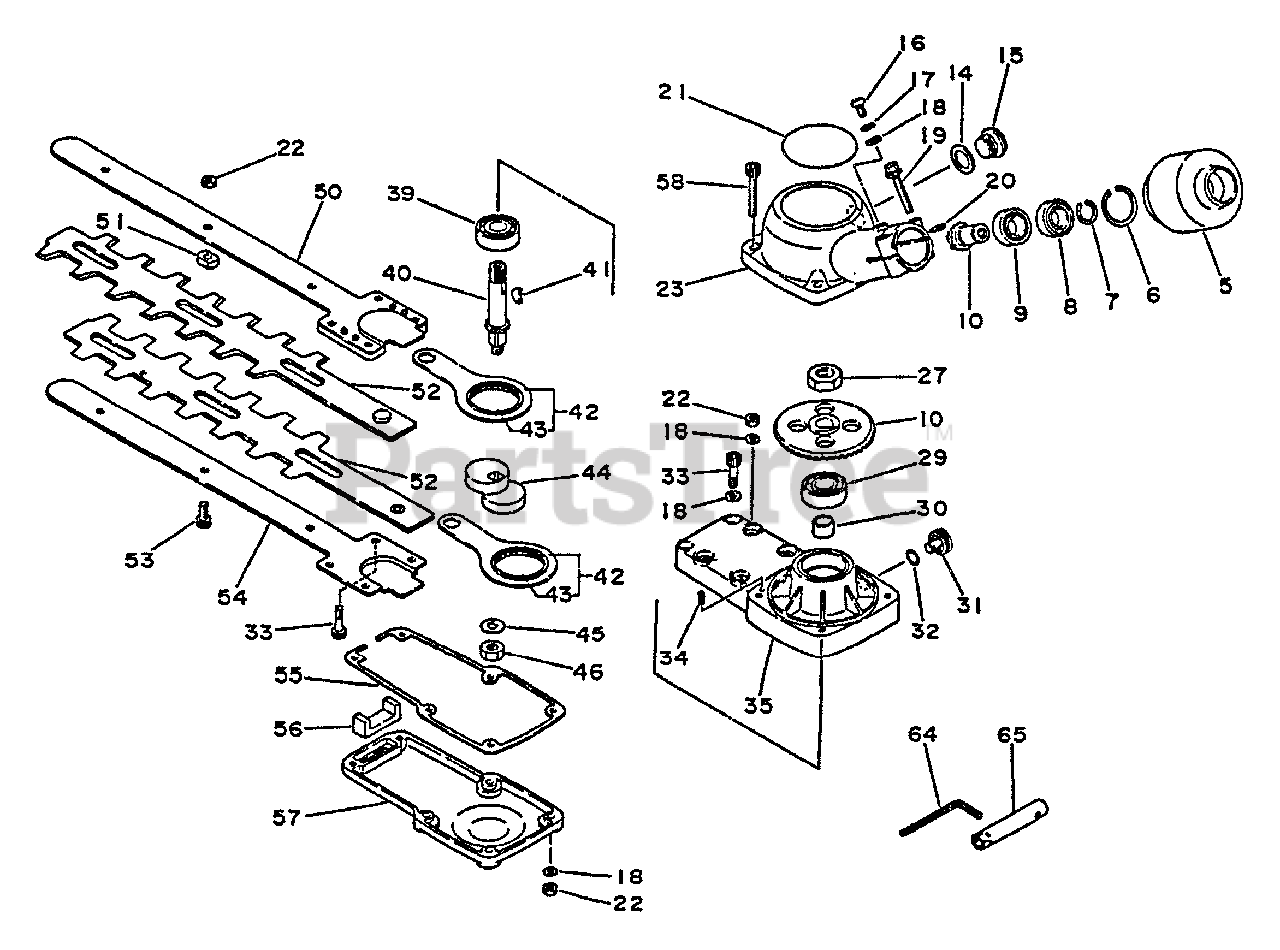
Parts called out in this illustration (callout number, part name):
6	RING, RETAINING - 28
7	RING, RETAINING - 12
8	BEARING, BALL - 6001
9	BEARING, BALL - 6001
10	GEAR SET
14	CASE, GEAR
15	FITTING, GREASE
16	SCREW - 5X10
17	LOCKWASHER - 5
18	WASHER - 5
19	BOLT - 5X35
21	LABEL
23	CASE, GEAR
27	NUT - 12
29	BEARING, BALL - 6201
30	SPACER
32	O-RING - 8
33	SCREW - 5X22
34	PIN - SPRING -- 3X10
35	HOUSING, CAM
39	BEARING, BALL - 6201
40	DRIVESHAFT
42	CONNECTING ROD ASSY
43	BEARING, NEEDLE
45	WASHER - 8
46	NUT - 8 -- LEFT HAND
50	SUPPORT, BLADE
52	SAW BLADE SET
53	SCREW - 5X14
54	SUPPORT, BLADE
55	GASKET, GEAR CASE
56	SEAL, FELT
57	LID, GEAR CASE
58	SCREW - 5X40
64	HEX KEY - 4mm
65	SOCKET WRENCH - 8mm
